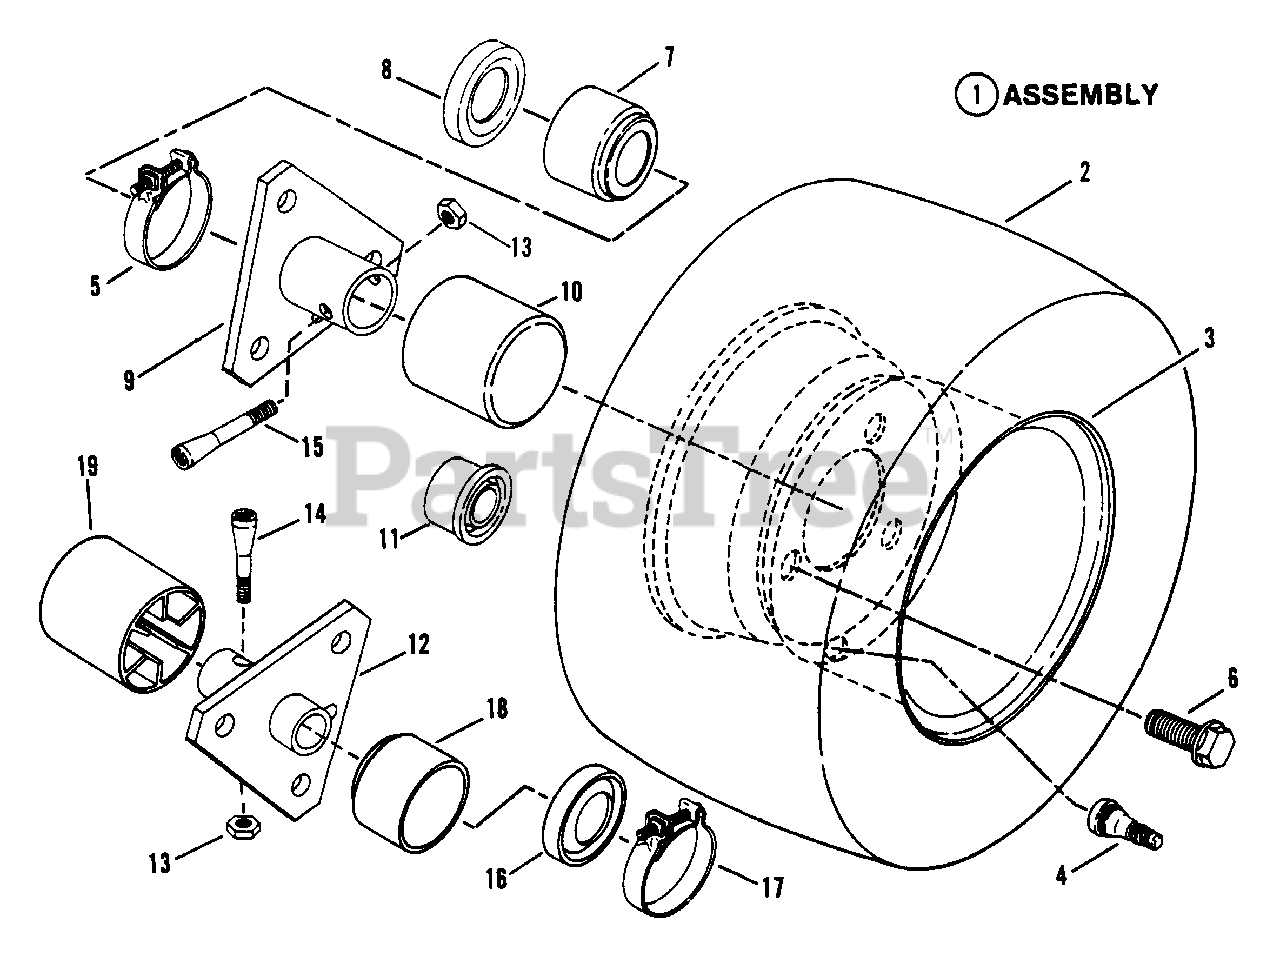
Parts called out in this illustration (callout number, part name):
1	ASSEMBLY, Rear Tire & Rim
2A	TIRE, Std., 16-4.80 x 8
2B	TIRE, Wide, 16-6.50 x 8
2C	TIRE, Ext Wide, 16-7.50 x 8
3A	RIM, Std.
3B	RIM, Wide,
3C	RIM, Ext Wide,
4	VALVE, Air (Snap-in)
5	CLAMP, Right Hand
6	BOLT, 1/2-20 x 3/4" Lug
7	BOOT, Right Hand
7A	BOOT, Right Hand
8	SEAL, Oil
9	HUB, Rear Wheel (Right Hand)
10	CAP, Hub
11	CAP, Seal L.H. 3/4"
12	HUB, Rear Wheel
13	NUT, 5/16-24 Hex Center Lock
14	BOLT, 5/16-24 x 1-5/8" Tapered (Left Hand)
15	BOLT, 5/16-24 x 2" Tapered (Right Hand)
16	SEAL, Oil (Left Hand)
17	CLAMP, (Left Hand)
18	BOOT, (Left Hand)
19	CAP, Hub (Left Hand)
